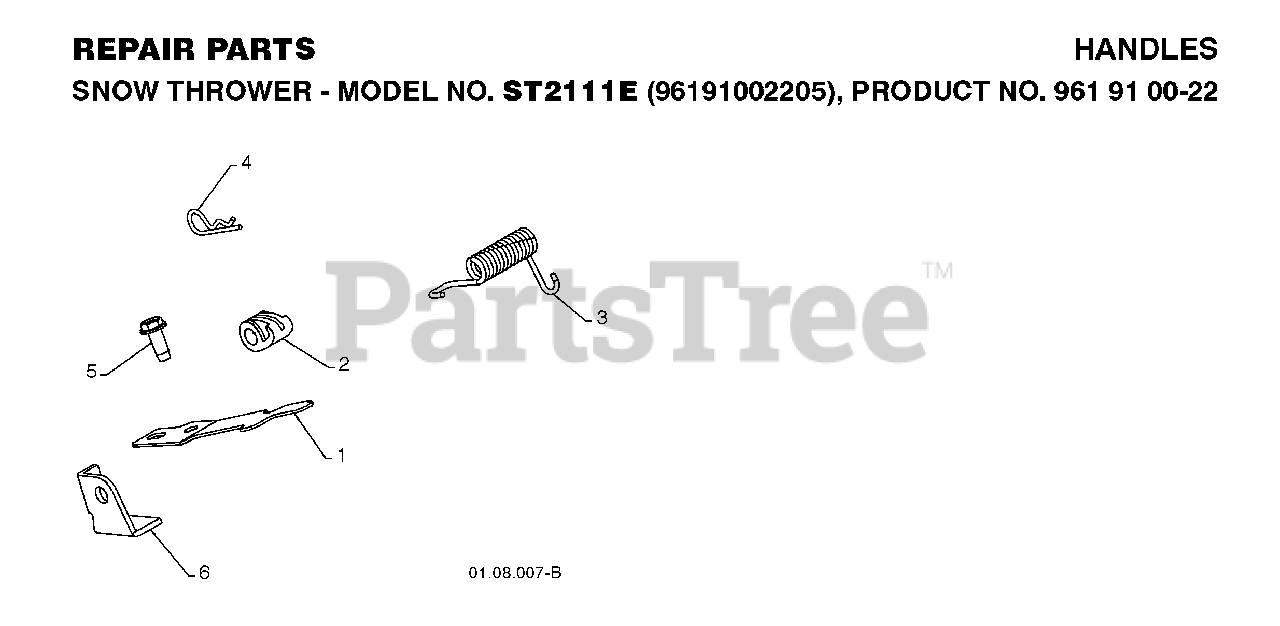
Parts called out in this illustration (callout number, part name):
1	SPRING.INTERLOCK
2	RP CAM.INTERLOCK.RELEASE
3	RP SPRING, TORSION
4	SPRING RETAINER
5	SCREW 14-20 X 5/8
6	STOP.INTERTLOCK.SPRING
